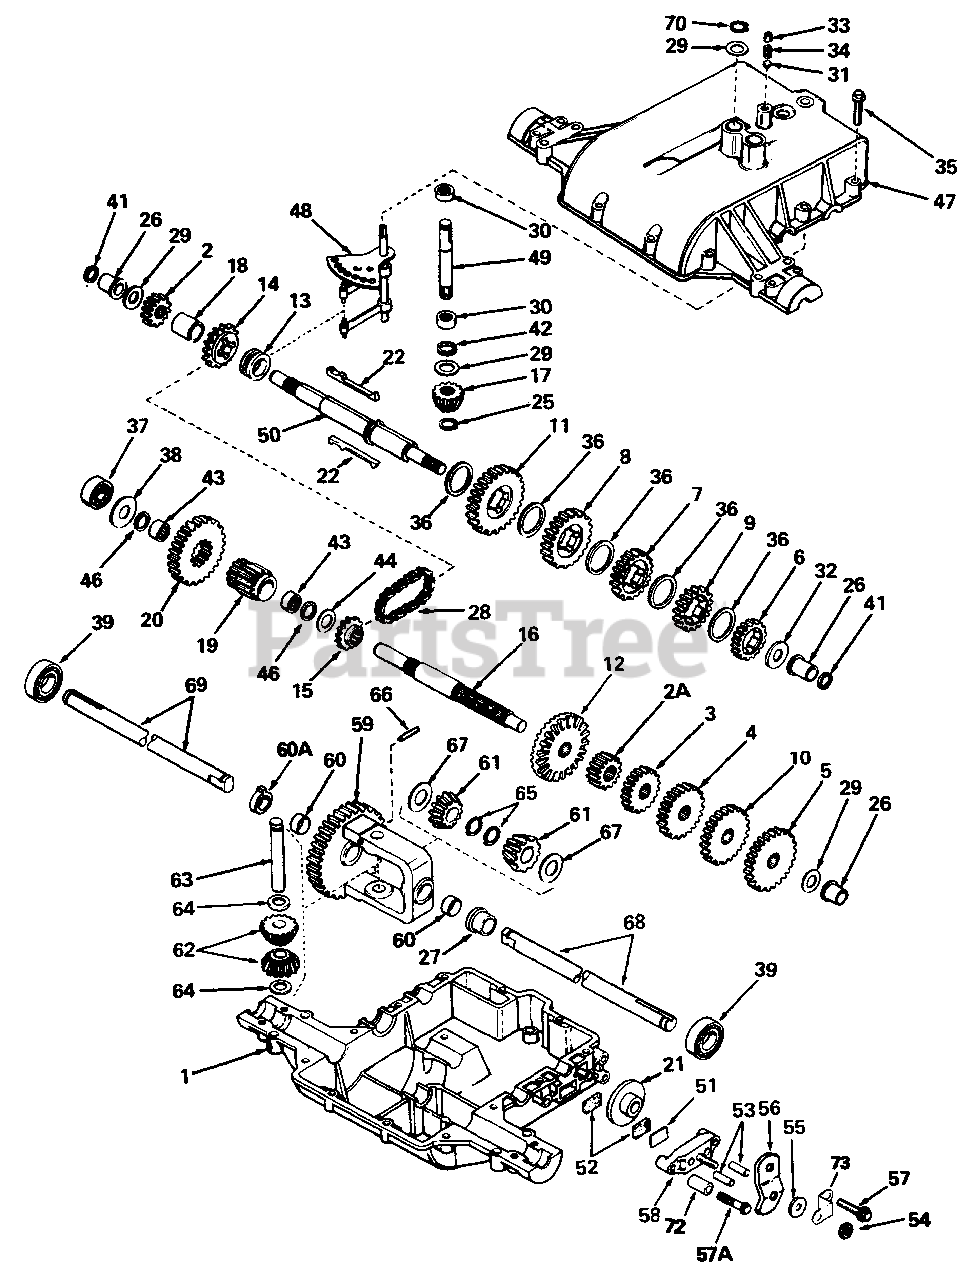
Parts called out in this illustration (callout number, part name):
1	CASE, Transaxle
2	GEAR, Spur (15 teeth)
2A	GEAR, Spur (12 teeth)
3	GEAR, Spur (20 teeth)
4	GEAR, Spur (25 teeth)
5	GEAR, Spur (30 teeth)
6	GEAR, Spur (20 teeth)
7	GEAR, Spur (25 teeth)
8	GEAR, Spur (30 teeth)
9	GEAR, Spur (22 teeth)
10	GEAR, Spur (28 teeth)
11	GEAR, Spur (37 teeth)
12	GEAR, Bevel (42 teeth)
13	COLLAR, Shift
14	SPROCKET (14 teeth)
15	SPROCKET (10 teeth)
16	SHAFT, Counter
17	BEVEL PINION, Input
19	PINION, Output
20	GEAR, Output
21	DISK, Brake
25	RING, Retaining
26	BUSHING, Flanged
27	BUSHING, Flanged
28	CHAIN, Roller (No. 41 chain, 22 links)
29	WASHER, Thrust
30	BEARING, Needle
31	BALL, Steel
32	WASHER, Thrust
33	SCREW, Set, 3/8-16 x 3/8
35	SCREW, Hex Hd., Thd. Form., 1/4-20 x 1-1/4
36	WASHER, Thrust
37	BEARING, Ball
38	WASHER, Flat
39	BEARING, Ball
41	SEAL, Square Cut
42	SEAL, Square Cut
43	BEARING, Needle
44	WASHER, Flat
46	SEAL, Square Cut
47	COVER, Transaxle
48	ROD & FORK ASSY., Shift
49	SHAFT, Input
50	SHAFT, Brake
51	PLATE, Brake Pad
52	PAD, Brake
53	PIN, Dowel
54	LOCKNUT, 5/16-24
55	WASHER, Flat
56	LEVER, Brake
57	SCREW, Hex Hd., Thd., Form., 1/4-20 x 1-1/4
57A	SCREW, Hex Hd., Thd., Form., 1/4-20 x 2-1/4
58	HOLDER, Brake Pad
59	GEAR ASSY., Differential (Incl. 2 of No. 60)
61	GEAR, Bevel
62	PINION, Bevel
63	PIN, Drive
64	WASHER, Thrust
65	RING, Retaining
66	PIN, Roll
67	WASHER, Thrust
68	AXLE (15-1/2" long)
69	AXLE (12-1/2" long)
70	RING, Retaining
